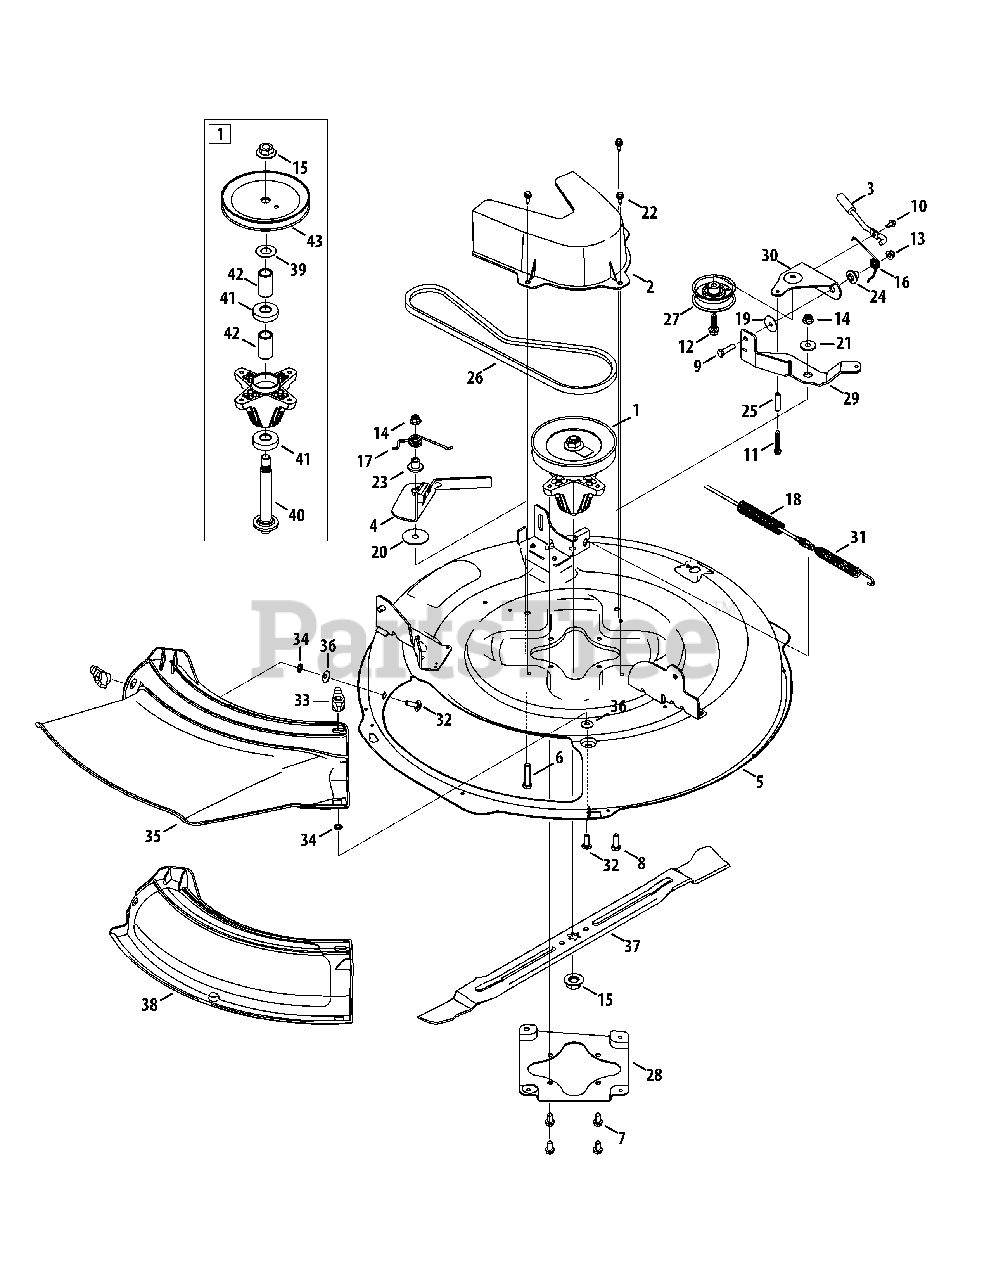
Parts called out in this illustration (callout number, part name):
1	Spindle Pulley Assembly, 6.3 DIA
2	Deck Belt Cover
3	Idler Rod Assembly
4	PTO Brake Assembly Bracket
5	Deck, 30" w/out Nozzle
6	Hex Cap Screw, 3/8-16 x 1.75
7	Tap Screw, 5/16-18, .750
8	Hex Head Screw, 3/8-16, 1.00
9	Hex Cap Screw, 5/16-18 x 1.25
10	Tap Scew, 1/4-20, 0.500
11	Tap Screw, 1/4-20, 1.750
12	Tap Screw, 3/8-16, 1.250
13	Flange Lock Nut, 5/16-18
14	Flange Lock Nut, 3/8-16
15	Flange Nut, 5/8-18
16	PTO Torsion Spring
17	Brake Torsion Spring
18	Compression Spring, .625 x 4.0
19	Flat Washer, .330x1.250x.060
20	Flat Washer, .406 x 1.920 x .060
21	Shoulder Spacer, .625 ID X .169
22	Shoulder Screw, .368 X.113: 1/4-20
23	Shoulder Spacer, .173 x .625 x .563
24	Shoulder Spacer, .134 x .500 x .438
25	Spacer, .260 X .372 X 1.420 LG
26	V-Type Belt, 43.5 LG
27	Flat Idler Pulley, 2.75 OD
29	Lower Floating Idler Bracket
30	Upper Floating Idler Bracket
31	PTO Cable
32	Carriage Screw, 5/16-18, 1.00
33	Wing Knob, 5/16-18
34	Speed Nut, .3125 ID
35	Chute Deflector
36	Bevel Washer, .340X.872X.060
37	Cutting Blade, 30.00" 3-IN-1
38	Mulch Plug
39	Shim Washer, .760X1.500X.030
40	Spindle Shaft, 6.11 LG.
41	Ball Bearing, .787ID X 1.85 ODX.551
42	Spacer, .792 X 1.060 X 1.860 LG
43	Deck Pulley, 6.3 DIA
